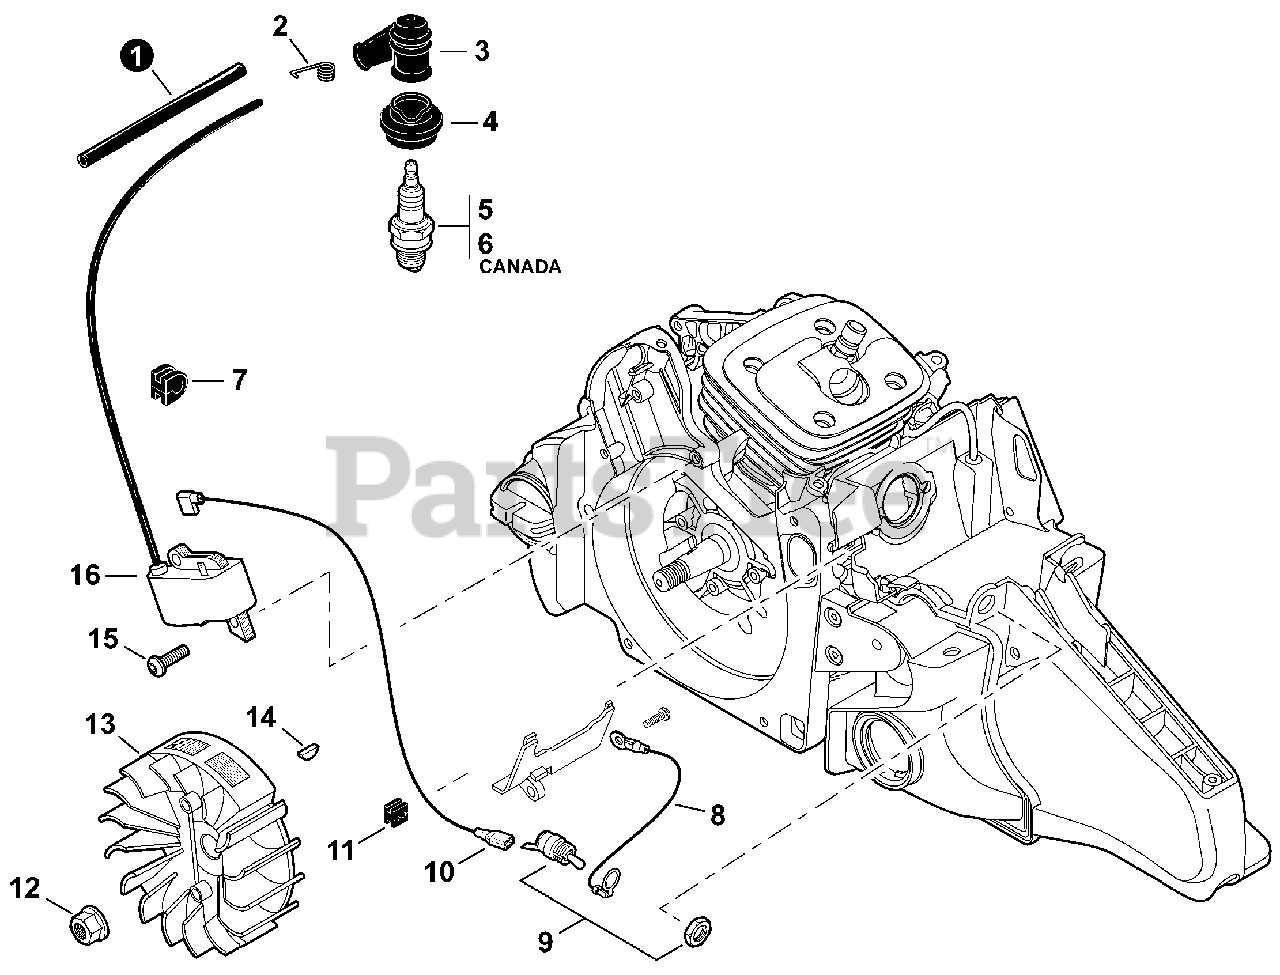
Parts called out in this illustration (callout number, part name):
1	TUBE, IGNITION COIL 6×7.2×70
2	TERMINAL, SPARK PLUG
3	CAP, SPARK PLUG
4	SEAL, SPARK PLUG
5	SPARK PLUG - BPM8Y
6	SPARK PLUG - BPMR8Y
8	LEAD - GROUND L= 170
9	SWITCH, ON-OFF
10	LEAD - IGNITION L= 280
11	GROMMET, LEAD
12	NUT, FLANGE M8
13	FLYWHEEL
14	KEY, WOODRUFF
15	BOLT, TORX 5×16
16	COIL, IGNITION
